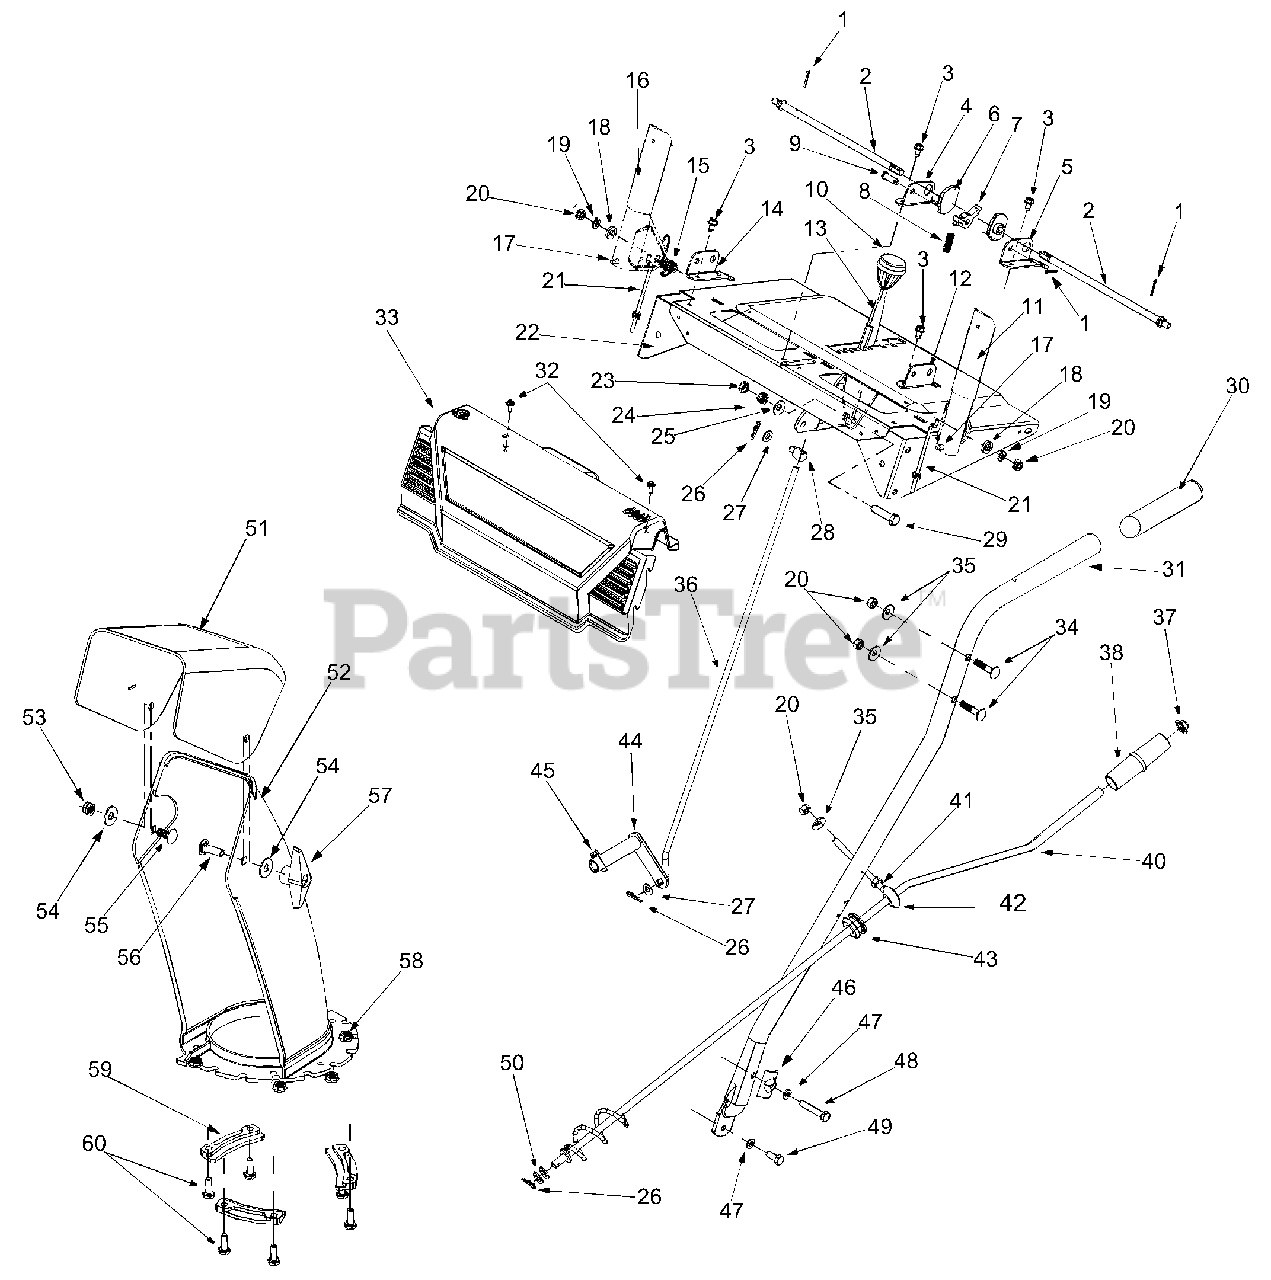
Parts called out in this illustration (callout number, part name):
1	Cotter Pin
3	Hex Washer Screw 1/4-20 x .5
6	Cam Lock Handle
7	Handle Lock Pawl
8	Compression Spring
9	Clevis Pin
10	Knob
11	Handle Assy - LH
15	Torsion Spring
16	Handle Assy - RH
17	Rubber Bumper
18	Washer
19	Lock Washer 5/16
20	Hex Nut 5/16-18
21	"Z" Fittings For Control Cables
24	Compression Spring
25	Bell Washer
26	Cotter Pin
27	Flat Washer 5/16
28	Ferrule
29	Hex Cap Screw 3/8-24 x 1.50
33	Handle Panel
34	Carriage Bolt 5/16-18 x 1.50
35	Bell Washer .340 ID x .872 OD
36	Shift Rod
37	Push Cap
38	Chute Directional Control Knob
40	Chute Directional Control Assembly
41	Hex Nut 5/16 - 18
42	Chute Directional Control Eyebolt
43	Rubber Grommet
45	Hex Washer Screw 1/4-20 x 1.0
46	Handle Tab
47	Lock Washer 5/16
48	Hex Cap Screw 5/16-18 x 1.75
49	Hex Cap Screw 5/16-18 x .75
50	Flat Washer
51	Upper Chute
52	Lower Chute
53	Hex Lock Nut 5/16-18
54	5/16 Washer
55	Carriage Bolt 5/16-18 x .75
56	Carriage Screw 5/16-18 x 1.0
58	Hex Lock Nut 1/4-20
59	Flange Keeper
60	Hex Cap Screw 1/4-20 x .75
